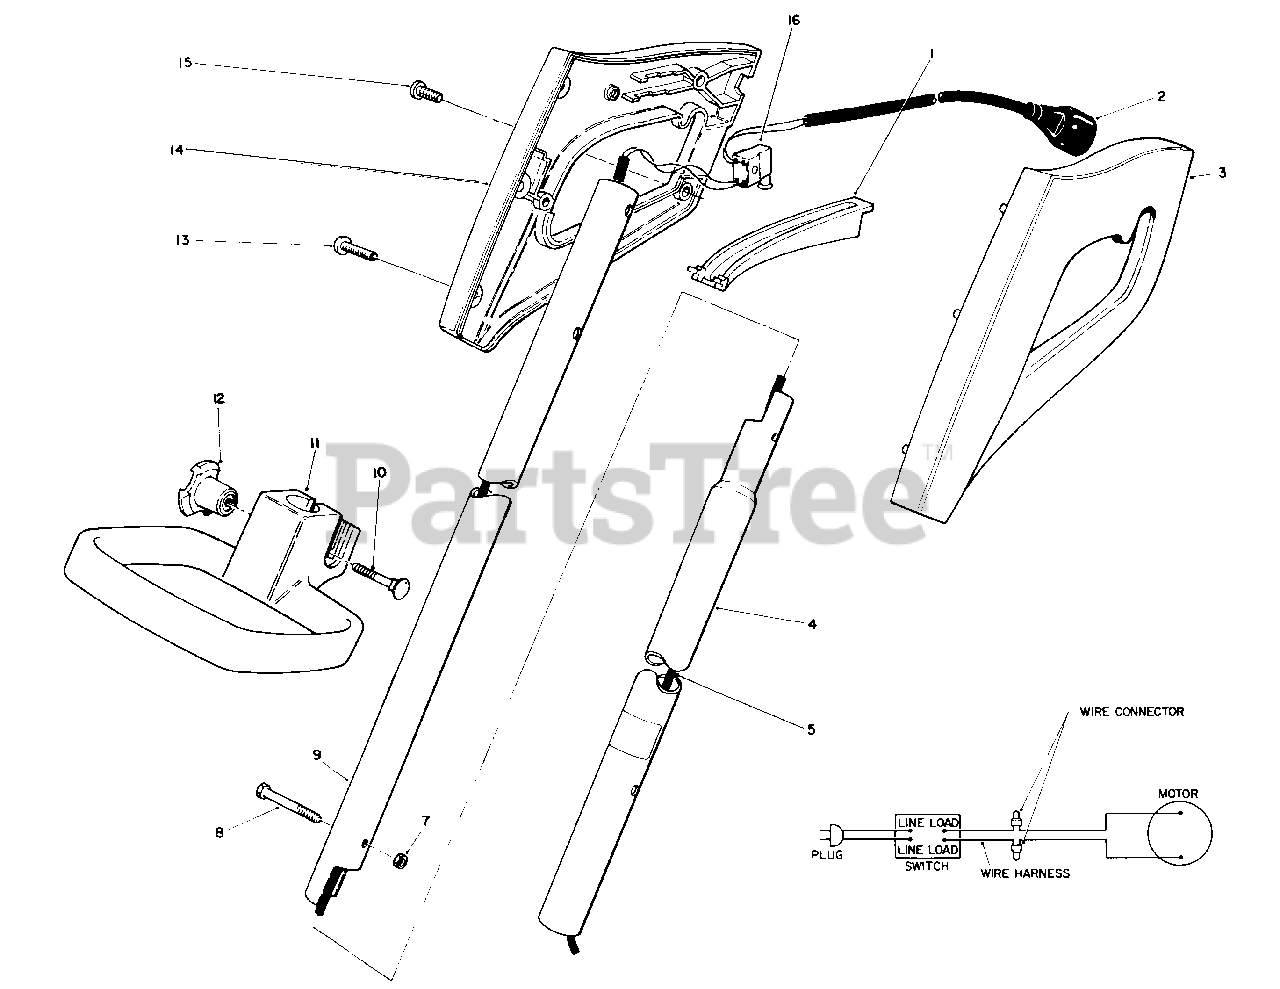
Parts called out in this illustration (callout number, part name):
1	Bar-Switch
2	Cord-Power
3	Grip-L.H.
4	Tube-Lower Extension
5	Wire Harness
7	Nut-Lock
8	Screw-Hex. Hd. Machine
9	Tube-Upper Extension
10	Bolt-Carriage
11	Handle-Adjustment
12	Knob-Adjustable
13	Screw-Thread Forming
14	Grip-R.H.
15	Screw-Thread Forming
16	Switch-Single Speed
